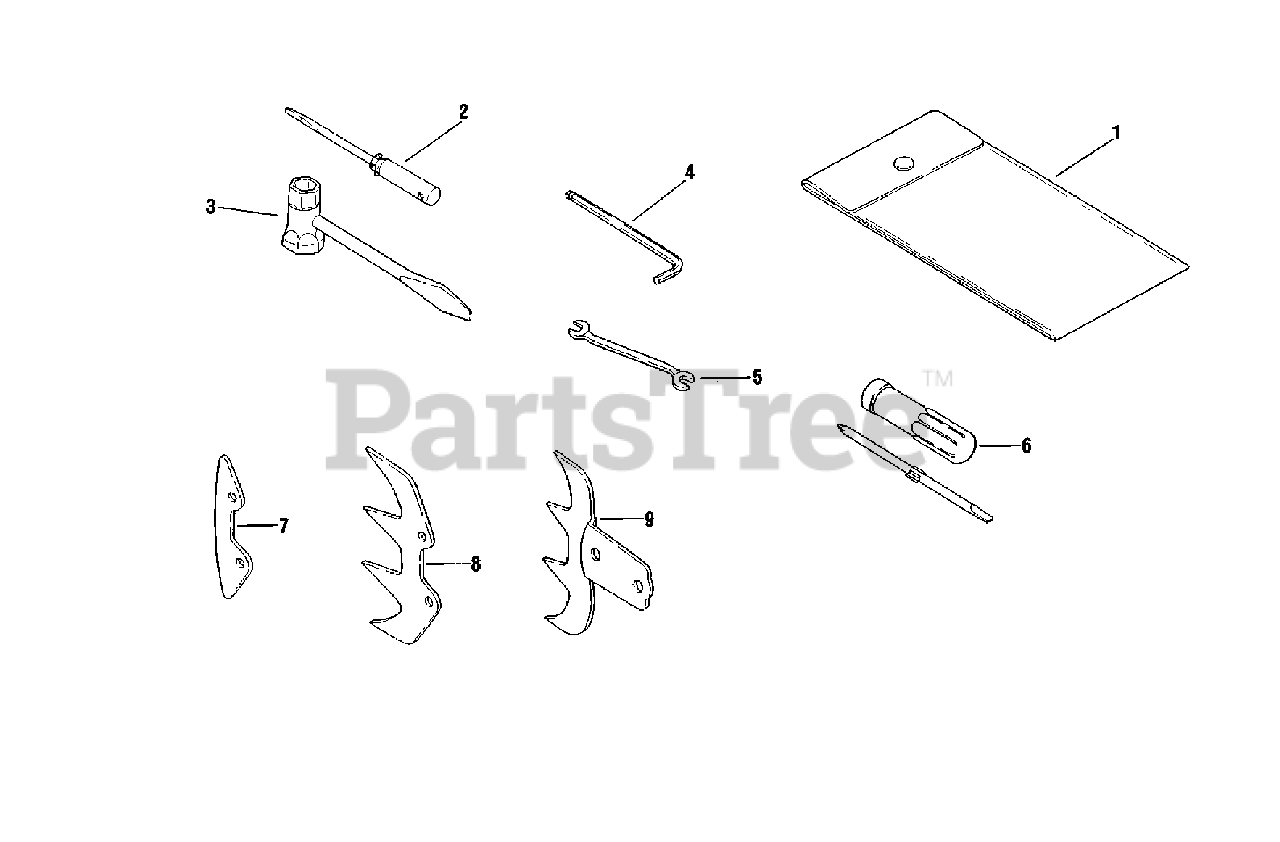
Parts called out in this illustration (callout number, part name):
1	BAG, TOOL
2	SCREWDRIVER
3	T-WRENCH
4	HEX KEY - 4mm
6	SCREWDRIVER
8	SPIKE
9	SPIKE
